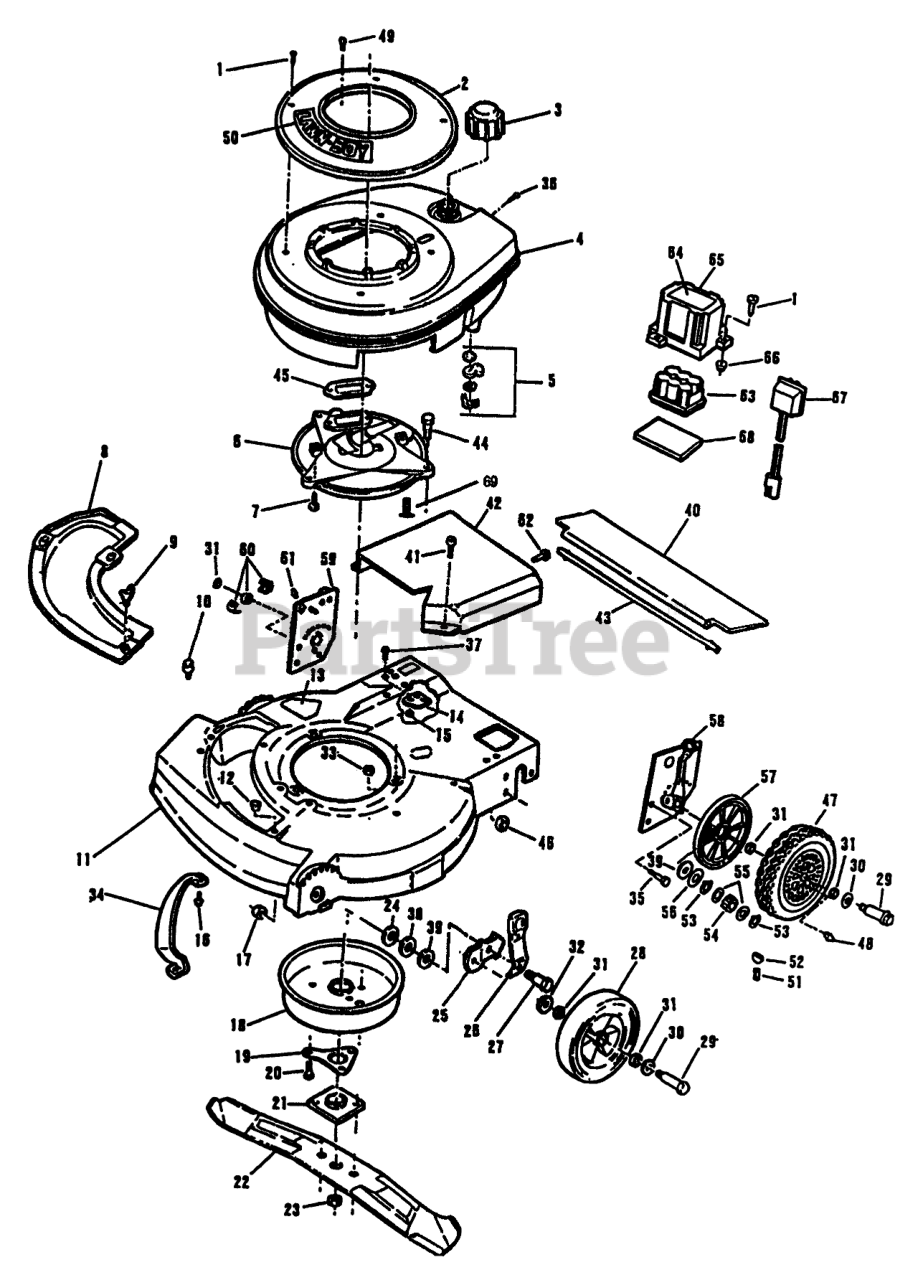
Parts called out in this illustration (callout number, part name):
1	SCREW S
2	STARTER BASE&NUTB
3	FUEL CAP & INSERT
4	Shroud-Engine
5	SHUT OFF VALVE KIT
6	PLATE F
7	SCREW V
8	CoverPlate
9	WING SCREW LAWRE
10	Bolt
11	Housing Assembly
12	Grommet
13	Decal
14	BOLSTER
15	LOCKNUT E
16	Screw
17	Nut
18	MUFFLER COVER F
19	SUPPORT F
20	SCREW
21	PLATE AND COLLAR ASM
22	21" Blade
23	NUT-BLADE
24	WASHER
25	Bracket
26	SPRING ARM ASM
27	BOLT
28	WHEEL&TIRE 6"
29	BOLT WHEEL
30	WASHER-PLAIN
31	WASHER
32	WASHER WROUGHT
33	NUT-LOCK F
34	BAR-TOE
35	Screw
36	SCREW S
37	Screw
38	WASHER
39	WASHER
40	SHIELD-TRAILING
41	SCREW SEMS TRM HEX HD
42	COVER DRIVE PL
43	ROD-TRAILING SHIELD
44	SCREW-HH
45	Gasket
46	NUT-LOCK F
47	Rear Wheel
48	FITTING LINCOLN
49	SCREW SEMS SM
50	APPLIQUE
51	SPRING
52	KEY
53	RET RING
54	PINION BROCKWAY
55	SPACER/GR ALGHNY
56	THRUST WASHER
57	W/COVER WHITE PL
58	HEIGHT ADJ AY-LH
59	HEIGHT ADJ AY-RH
60	REAR AXLE BEARING
61	FITTING LINCOLN
62	SCREW
63	Battery-12V
64	Decal-Batt.
65	COVER BATTERY PL
66	NUT-CLIP
67	Float
68	PAD-BATTERY
69	SCREW-SEMS F
